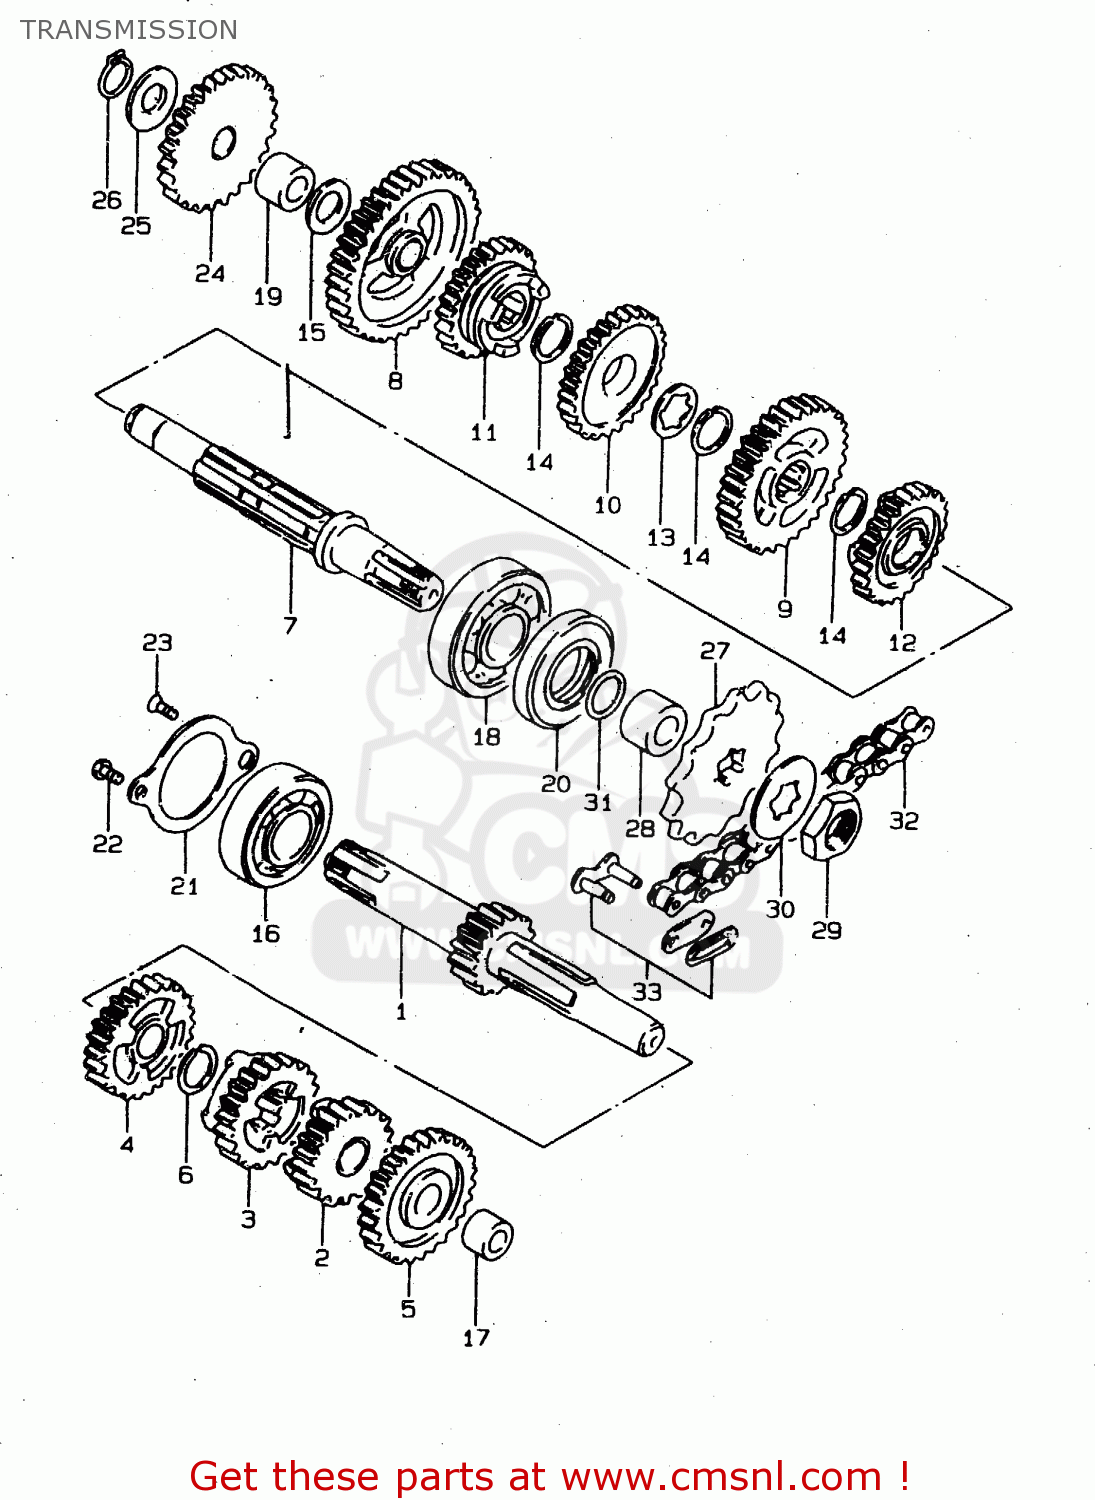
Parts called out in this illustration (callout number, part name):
1	SHAFT,COUNTER(NT:13)
2	GEAR,2ND DRIVE(NT:19)
3	GEAR,3RD DRIVE(NT:22)
4	GEAR,4TH DRIVE(NT:24)
5	GEAR,FIFTH DRIVE
6	CIRCLIP
7	SHAFT,DRIVE
8	GEAR,1ST DRIVEN(NT:35)
9	GEAR,2ND DRIVEN(NT:32)
10	GEAR,3RD DRIVEN(NT:29)
11	GEAR,4TH DRIVEN(NT:36)
12	GEAR,5TH DRIVEN(NT:24)
13	WASHER(13X24X1)
14	CIRCLIP
15	WASHER,LOCK
16	BEARING(17X40X12)
17	BUSH
18	BEARING
19	BUSH
20	SEAL,OIL(21X40X6)
21	RETAINER,CNTR SHAFT BEARING
22	SCREW
23	SCREW
24	GEAR,KICK STARTER IDLE
25	WASHER
26	CIRCLIP,12 MM
27	SPROCKET,ENGINE
28	SPACER(17X21X13)
29	NUT
30	WASHER,LOCK
31	O RING(D:1,ID:16.8)
32	CHAIN,DRIVE
33	JOINT,CHAIN
